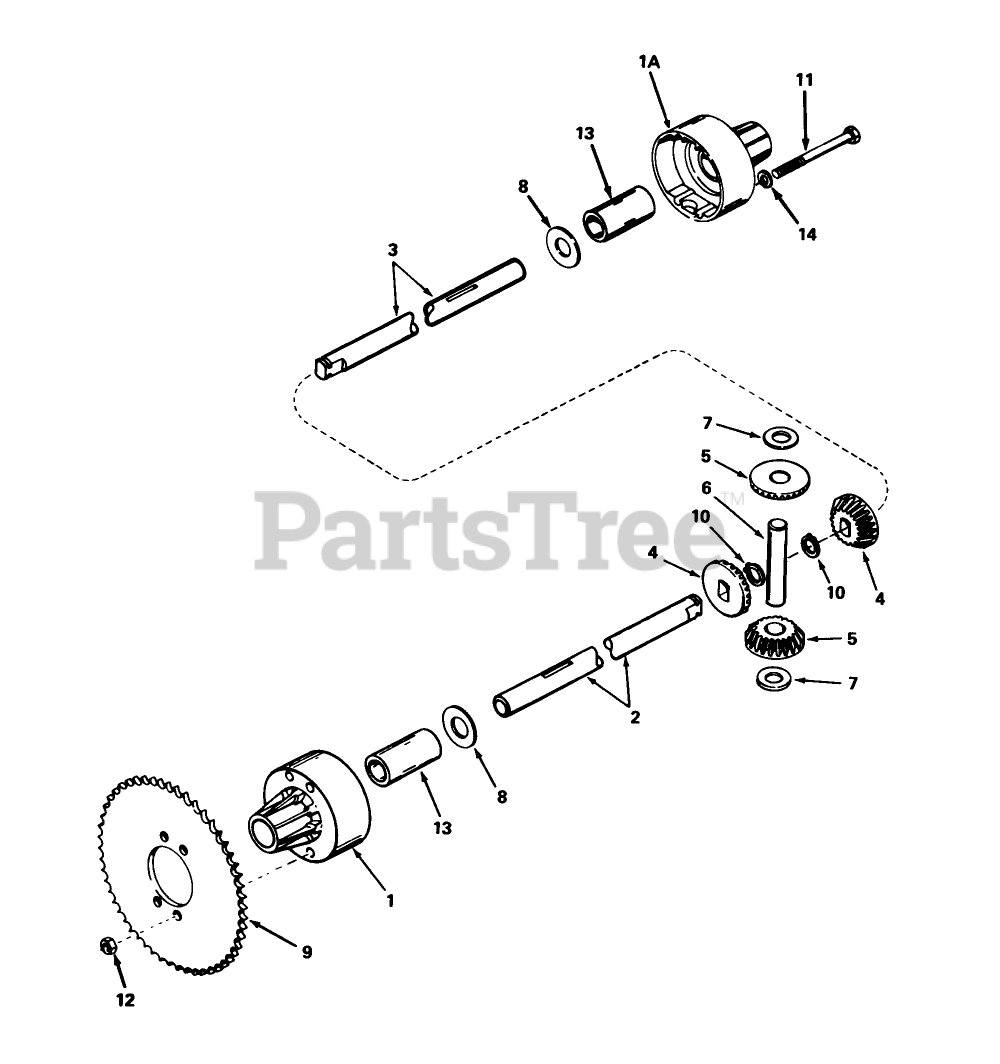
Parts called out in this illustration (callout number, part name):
1	Housing, Differential Carrier (Incl. Ref. #13)
1A	Housing, Differential Carrier (Incl. Ref. #13)
2	Axle (9-1/8" Long)
3	Axle (18-5/8" Long)
4	Bevel Gear
5	Gear Pinion
6	Pin Drive
7	Washer Thrust
8	Washer
9	Sprocket
10	Ring-Snap
11	Screw-Hex Hd.
12	Nut-Lock
13	Bushing
14	Washer
